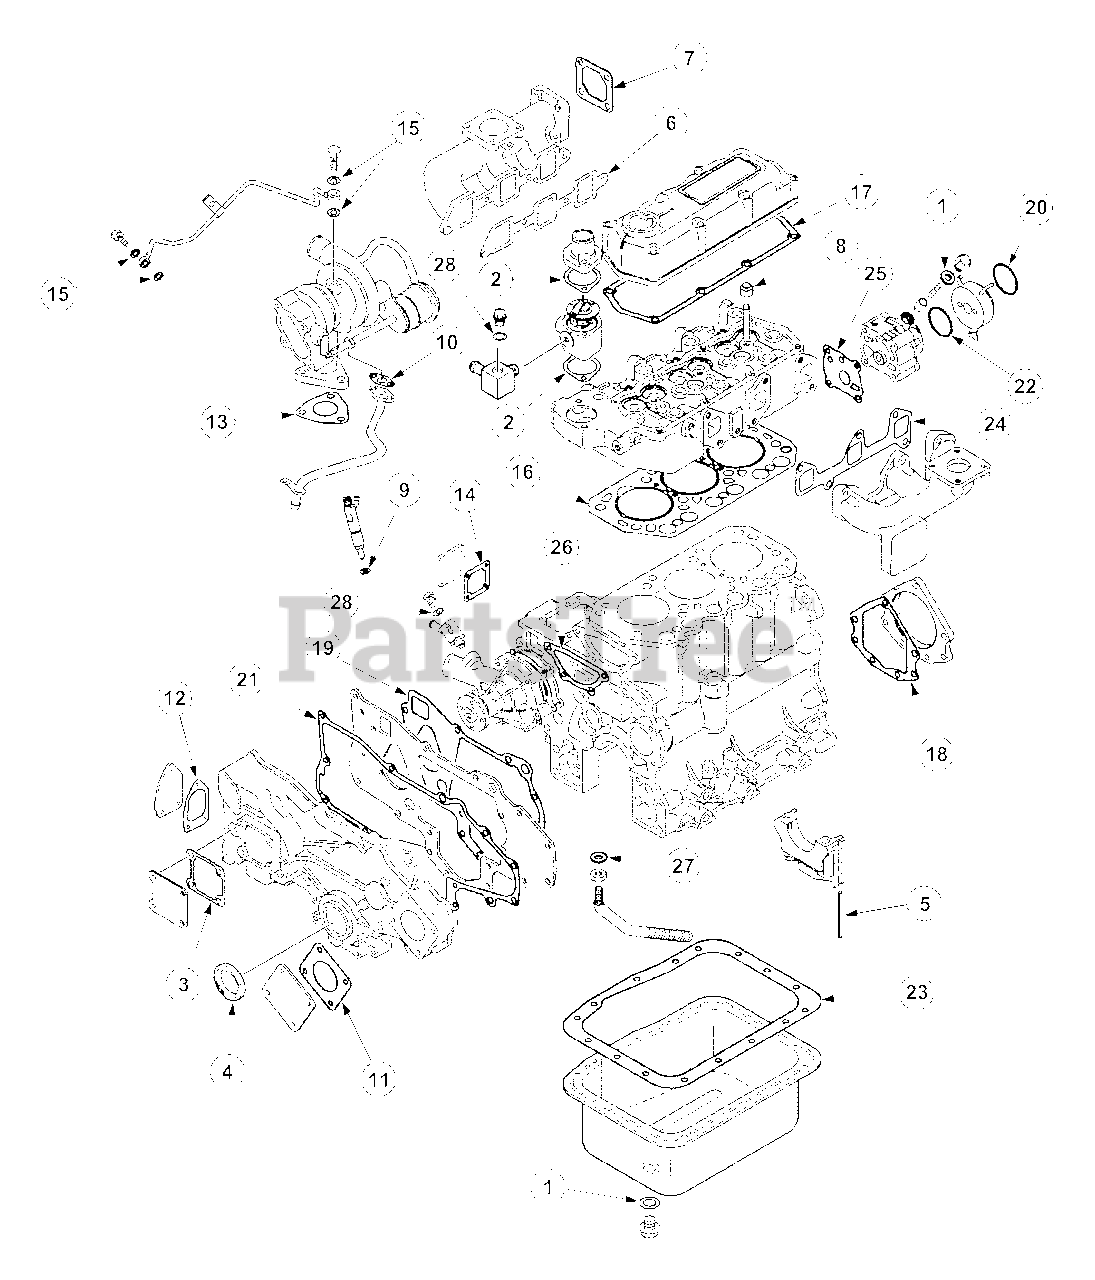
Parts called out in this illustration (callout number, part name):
1	Gasket,Oil Drain
2	Gasket,Water
4	Seal,Front Oil
6	Gasket,Intake Manifold
7	Gasket,Air Heat
8	Seal,Valve Stem
9	Gasket,Nozzle
11	Gasket,Oil Pump
12	Gasket,Governor
14	Gasket,Tie Rod
15	Gasket
16	Gasket,Cylinder
17	Gasket,Rocker
18	Gasket,Oil Seal
20	O-Ring
23	Gasket,Oil Pan
24	Gasket,Exhaust
25	Gasket,Oil Pump
28	Gasket
